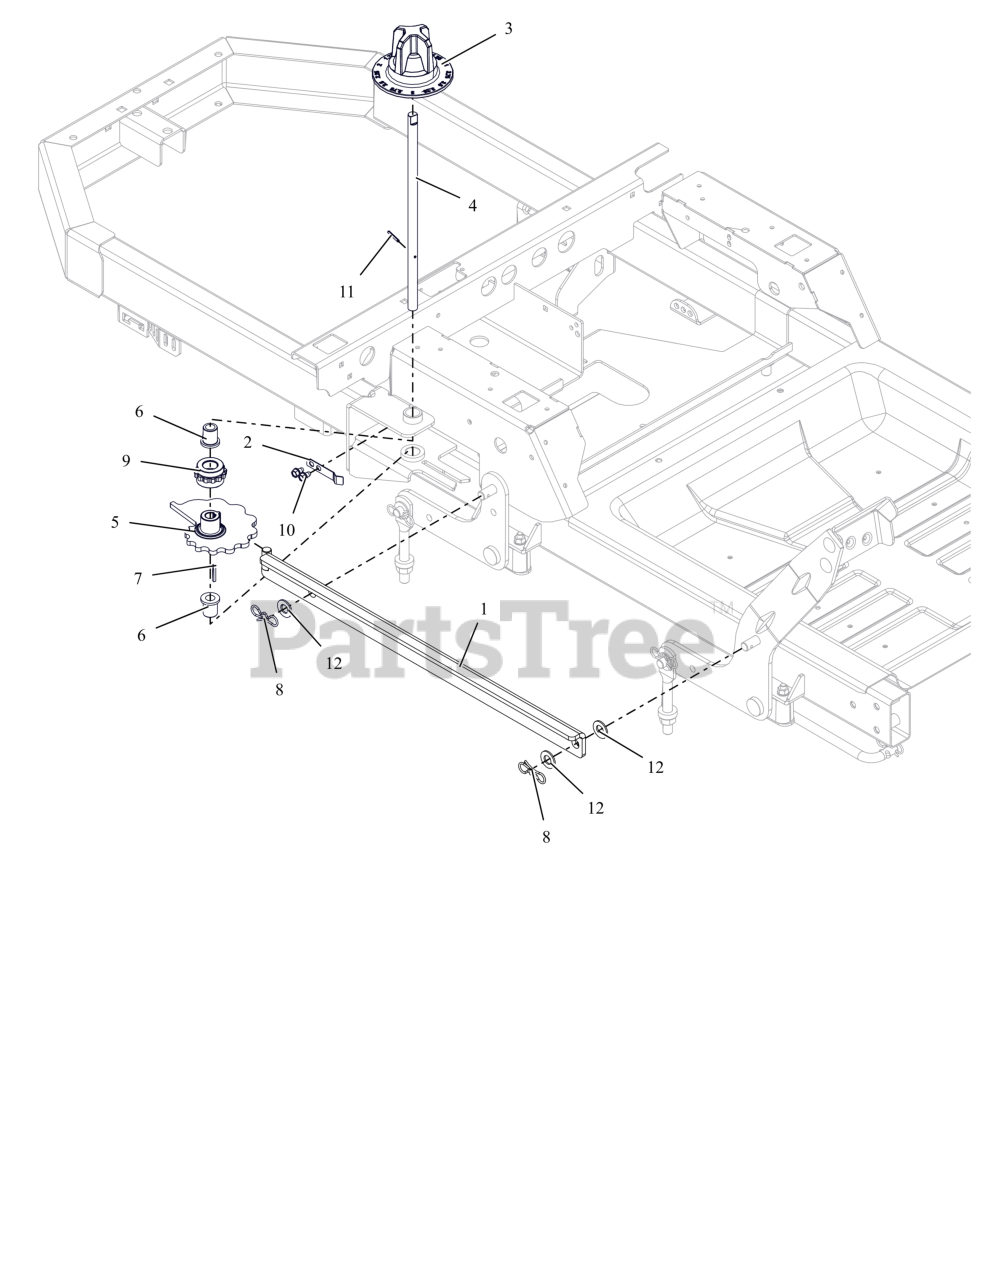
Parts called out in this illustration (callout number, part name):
1	WLDMT, HOC LINK
2	ARM, HOC DETENT
3	KNOB, HOC DIAL
4	SHAFT, HOC CAM IKON
5	CAM, HOC (PM)
6	BSHG-FLG, .503X.750X.875X1.00
7	KEY, 1/8 X 1/8 X 1.0
8	PIN, BOWTIE .091X1.875 ZCC
9	GEAR, HOC INDEX
10	SCR,TAP .25-20X.375 HWH TR ZCC
11	PIN-ROLL .125X1.00
12	WSHR-FL-NYL .518X1.000X.080
